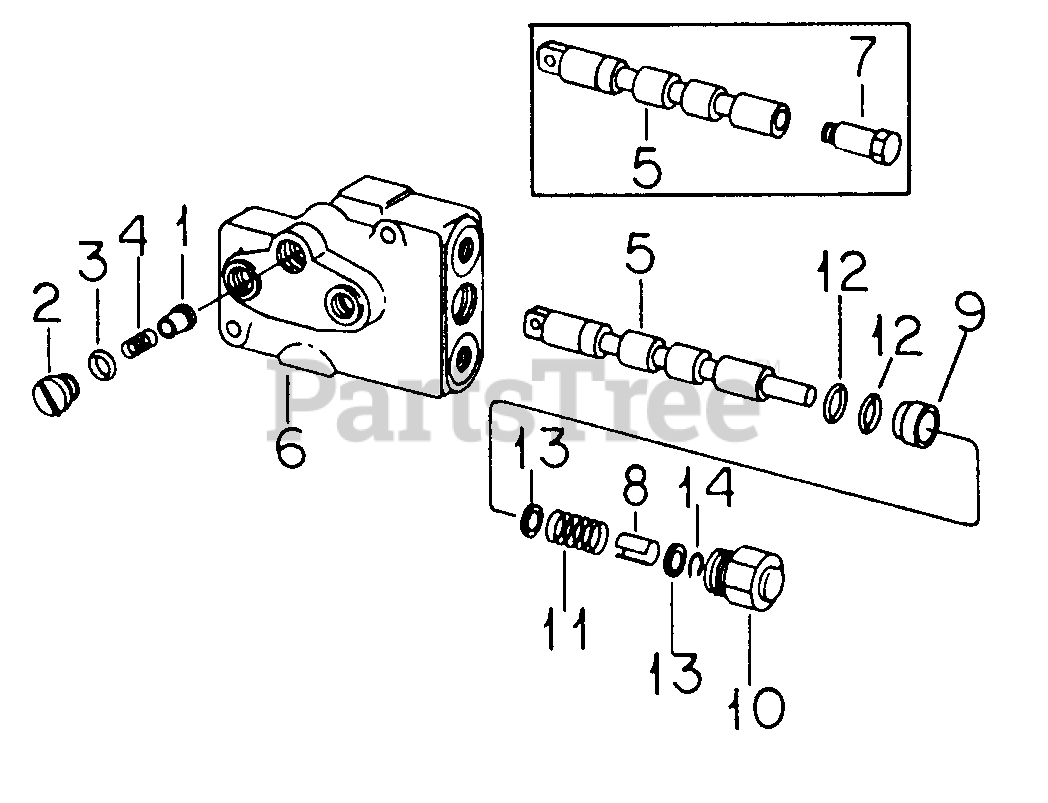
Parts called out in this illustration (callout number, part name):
1	Plunger, Lift Check
2	Plug, Lift Check
3	O-Ring, 3/8 X 9/16 X 3/32
4	Spring, Lift Check
5	Spool
6	Body
7	Screw, Spool
8	Spacer, Spool
10	Cap
11	Spring, Spool Center
12	O-Ring, 1/2 X 11/16 X 3/32
13	Washer, .020
14	Ring, Retainer
